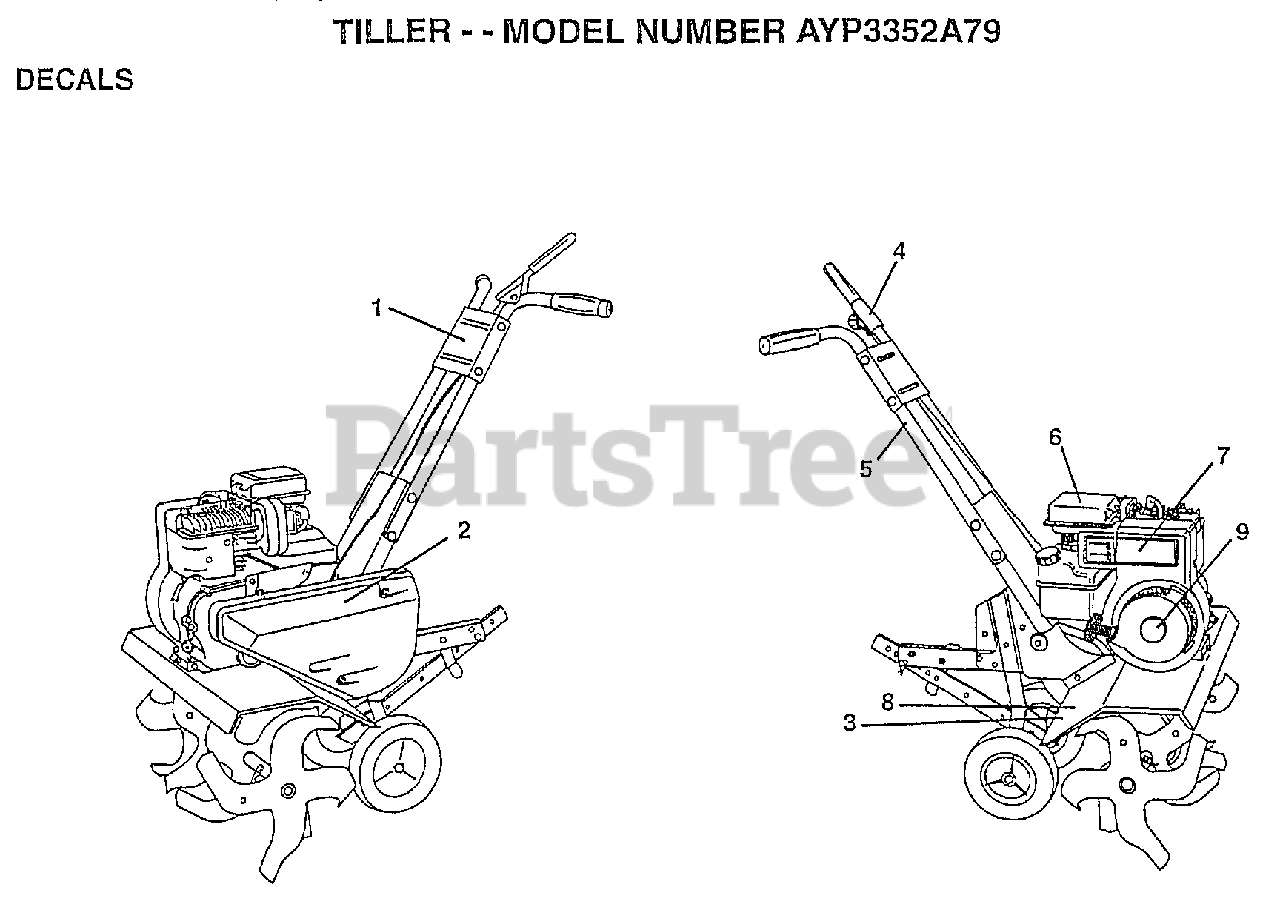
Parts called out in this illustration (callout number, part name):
1	DECAL.CNTRL.PNL.5
2	DECAL.LOGO
4	DECAL TI
5	DECAL TI
7	DECAL, BRIGGS & STRATTON
8	DECAL TI
9	DECAL, 5 HP
